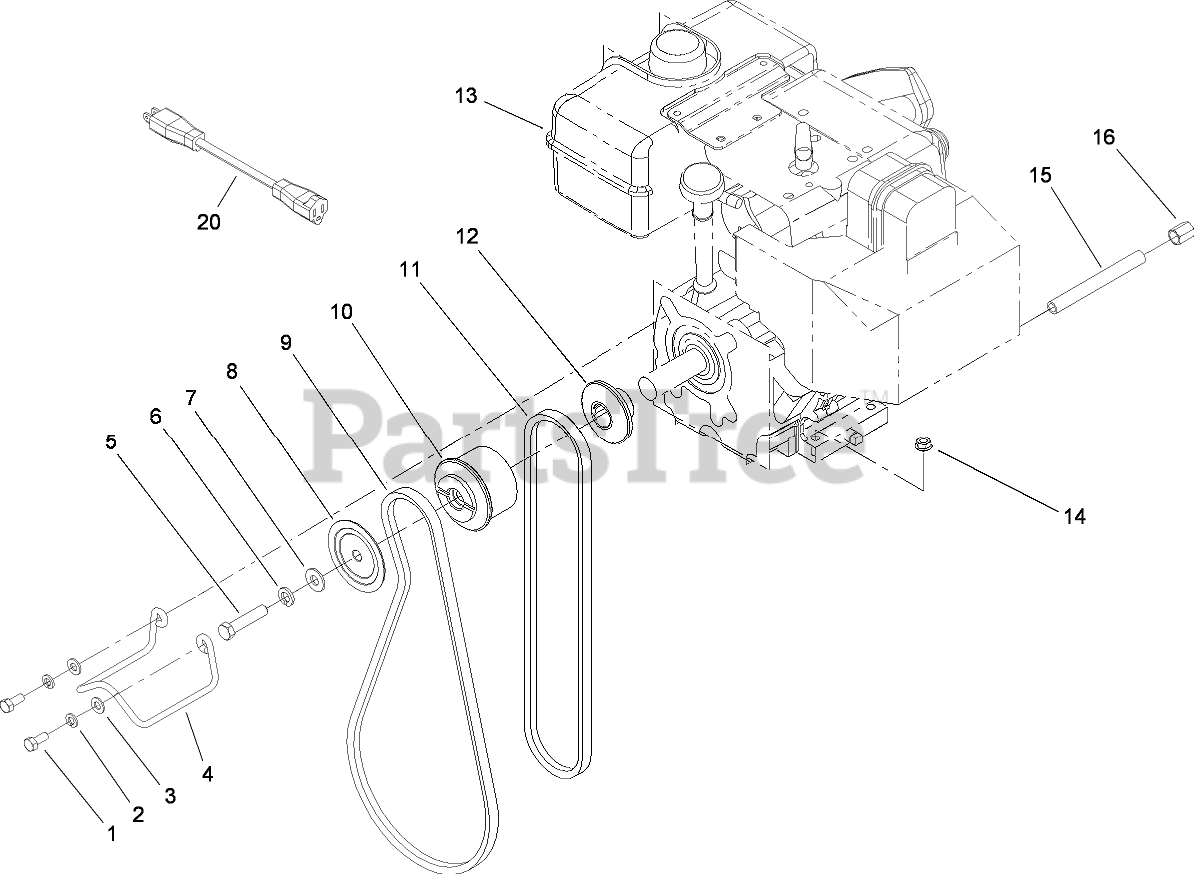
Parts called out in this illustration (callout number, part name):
1	SCREW-HH
2	WASHER-LOCK
3	WASHER-PLAIN
4	GUIDE-BELT
5	SCREW-HH
6	WASHER-LOCK
7	WASHER-FLAT
8	SHEAVE-HALF, IMPELLER
9	BELT-V
10	PULLEY-ENGINE, CENTER
11	V BELT-TRACTION
12	SHEAVE-HALF, TRACTION
14	NUT-HF
15	NIPPLE-PIPE
16	CAP-PIPE
20	CORD-EXTENSION
